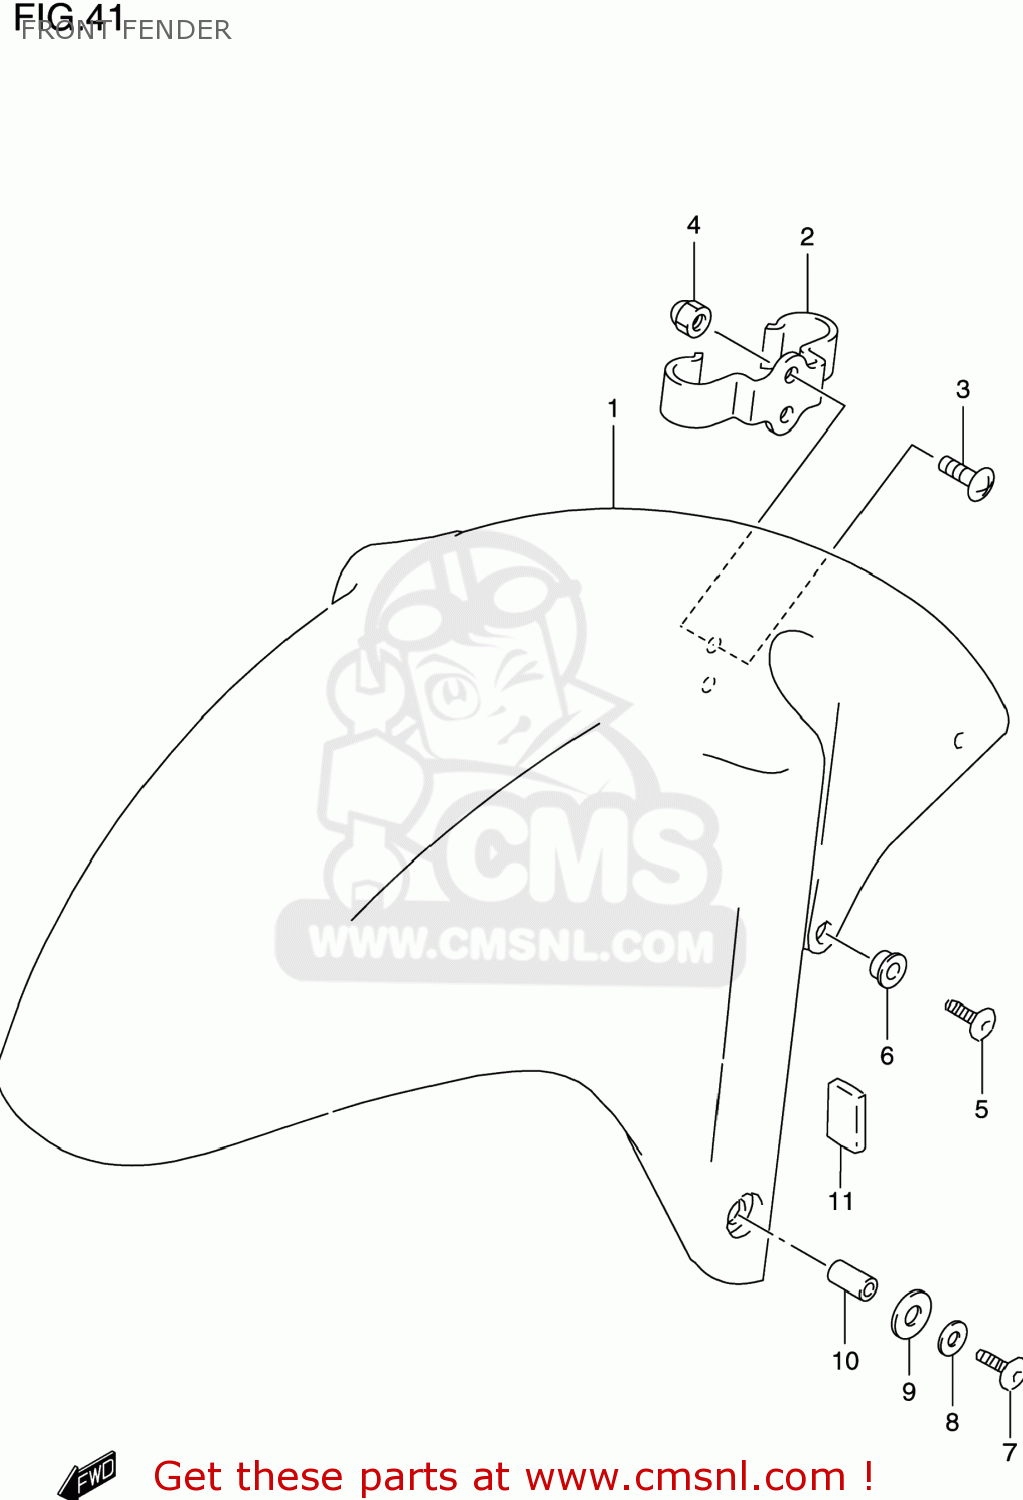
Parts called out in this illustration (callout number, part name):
1	FENDER,FR
2	CLAMP,BRAKE HOSE
3	SCREW
4	NUT
5	SCREW(6X16)
6	WASHER(6.3X16X1.5)
7	SCREW(6X16)
8	WASHER(6.5X16X1.2)
9	WASHER,FR FENDER FR NO.2
10	SPACER(6.5X9X6.7)
11	CUSHION
